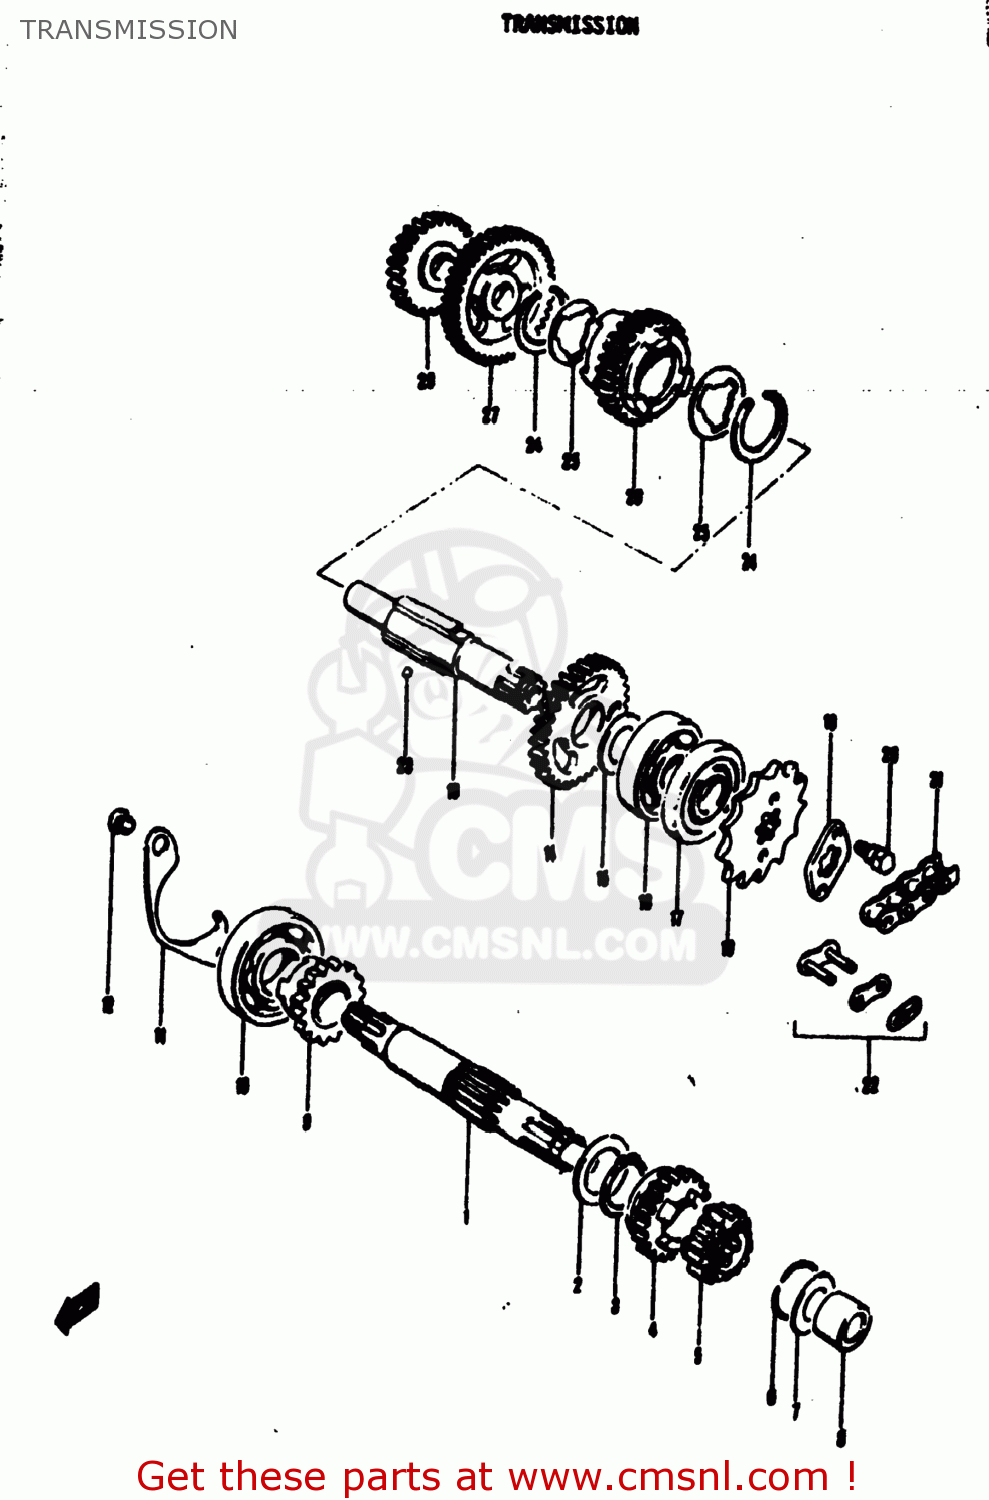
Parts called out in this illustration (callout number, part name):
1	SHAFT,COUNTER(NT:11)
2	WASHER(21X30X1)
3	CIRCLIP
4	GEAR,3RD DRIVE
5	GEAR,2ND DRIVE
6	CIRCLIP
7	WASHER
8	BUSH(12X19X11)
9	GEAR,KICK STARTER DRIVEN(NT:16
10	BEARING(30X62X10)
11	PLATE,COUNTERSHAFT BEARING
12	SCREW
13	DRIVE SHAFT
14	GEAR,SECOND DRIVEN
15	WASHER,THRUST
16	BEARING
17	SEAL,OIL(17X40X7)
18	SPROCKET,ENGINE
19	ENGINE SPROCKET PLATE
20	BOLT
21	CHAIN ASSEMBLY,DRIVE
22	JOINT ASSEMBLY,CHAIN
23	BALL
24	RING,SNAP
25	WASHER,LOCK
26	3RD DRIVEN GEAR
27	1ST DRIVEN GEAR
28	GEAR,KICK STARTER IDLE
